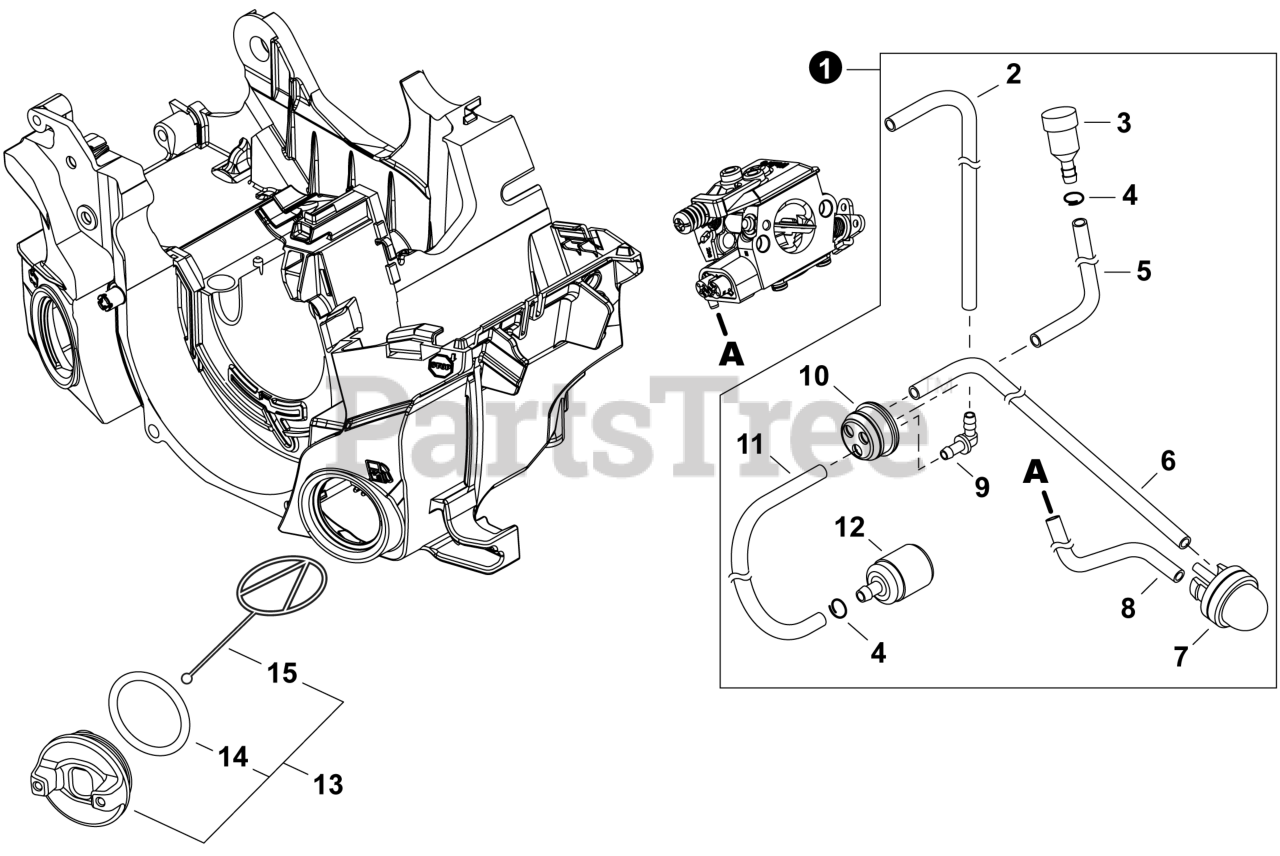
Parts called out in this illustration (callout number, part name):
1	FUEL SYSTEM KIT
2	PIPE, FUEL 3x5x85 BLACK
3	VENT ASSY
5	PIPE, FUEL 3x5x70 BLACK
6	PIPE, PURGE 2.4x5x140 BLACK
7	BULB, PURGE
8	PIPE, FUEL 2.4x5x105 BLACK
9	CONNECTOR, PIPE
10	GROMMET, FUEL 5
11	PIPE, FUEL 3x5x120 BLACK
12	FILTER, FUEL
13	CAP ASSY, FUEL
14	O-RING 29
15	CONNECTOR, CAP L= 60 MM
